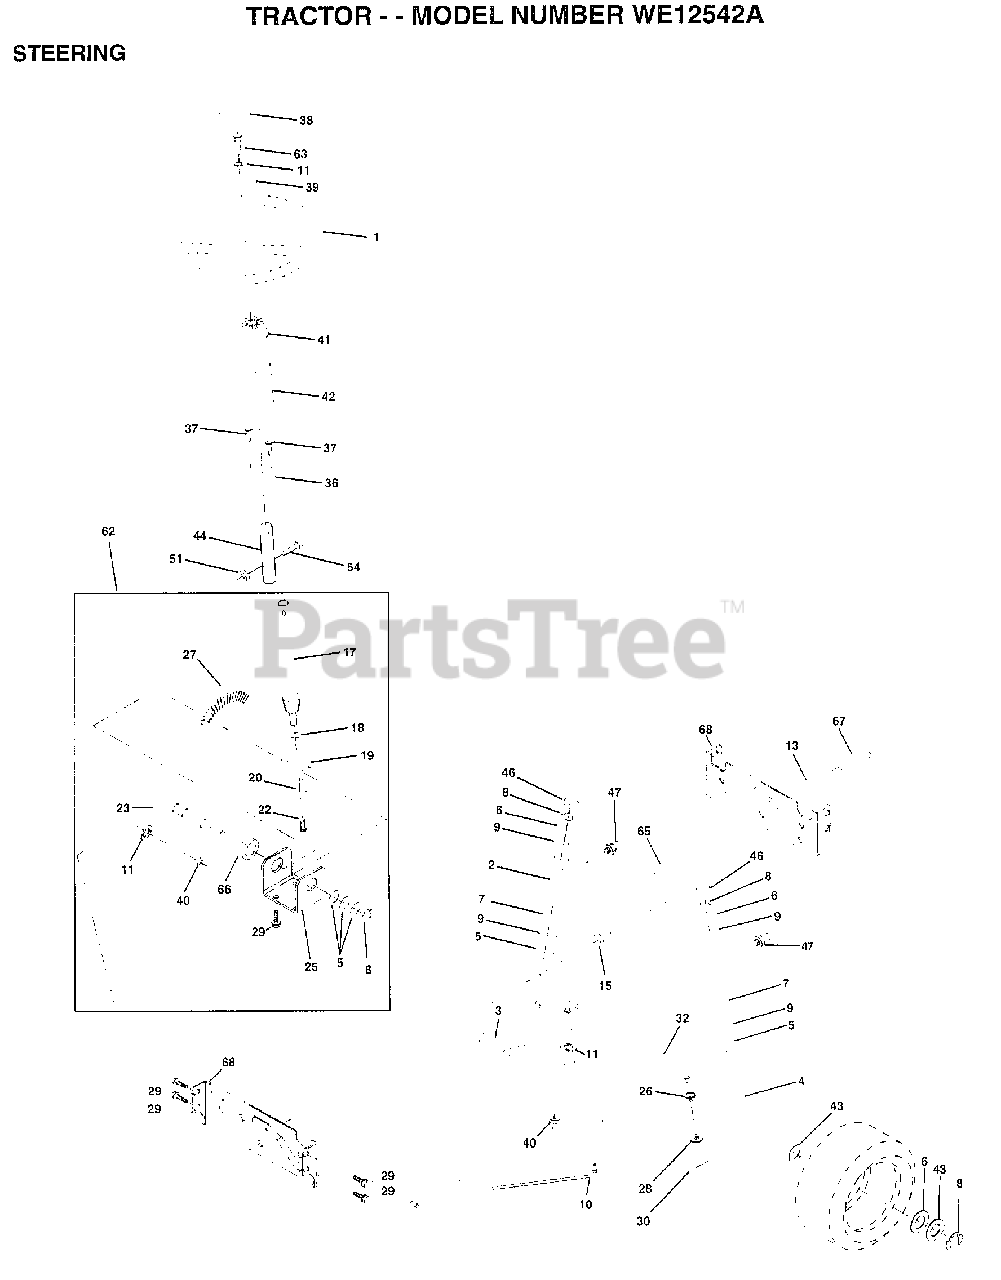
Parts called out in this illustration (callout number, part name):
1	WHEEL STR AYP BLK
2	AXLE ASM
3	SPINDLE.ASM.LH
4	"SPINDLE ASM,RH"
5	WASHER .T
6	WASHER
7	WASHER
8	RING
9	COL. SRTG. BEAR.
10	DRAGLINK-STAMPED
11	LOCKWASHER
13	BEARING AXLE
15	"NUT-LOC,FLANGE LT"
17	SHAFT ASM STEERIN
18	THRUST WASHER
19	SUPPORT.SHAFT
22	SCREW HEX SOC1/4-
25	BRKT-STEERING
26	BUSHING.DRAGLINK
27	GEAR SECTOR
28	WASHER
29	SCREW
30	COTTER PIN
32	TIE ROD
36	BUSHING.STEERING
37	"SCREW-TT,10-32 FL"
38	CAP STEER AYP
39	WASHER T
40	GRIPCO NUT
41	ADAPTER LT
42	BOOT.STEER.PL
43	WASHER
44	SCREW.SELF.TAP.10
46	CAP
47	ZERK M
51	NUT
54	BOLT
62	KIT STEERING ASM
63	BOLT
65	SPACER AXLE
66	"BEARING-ARM,PITMA"
67	BOLT
68	BRACE AXLE
